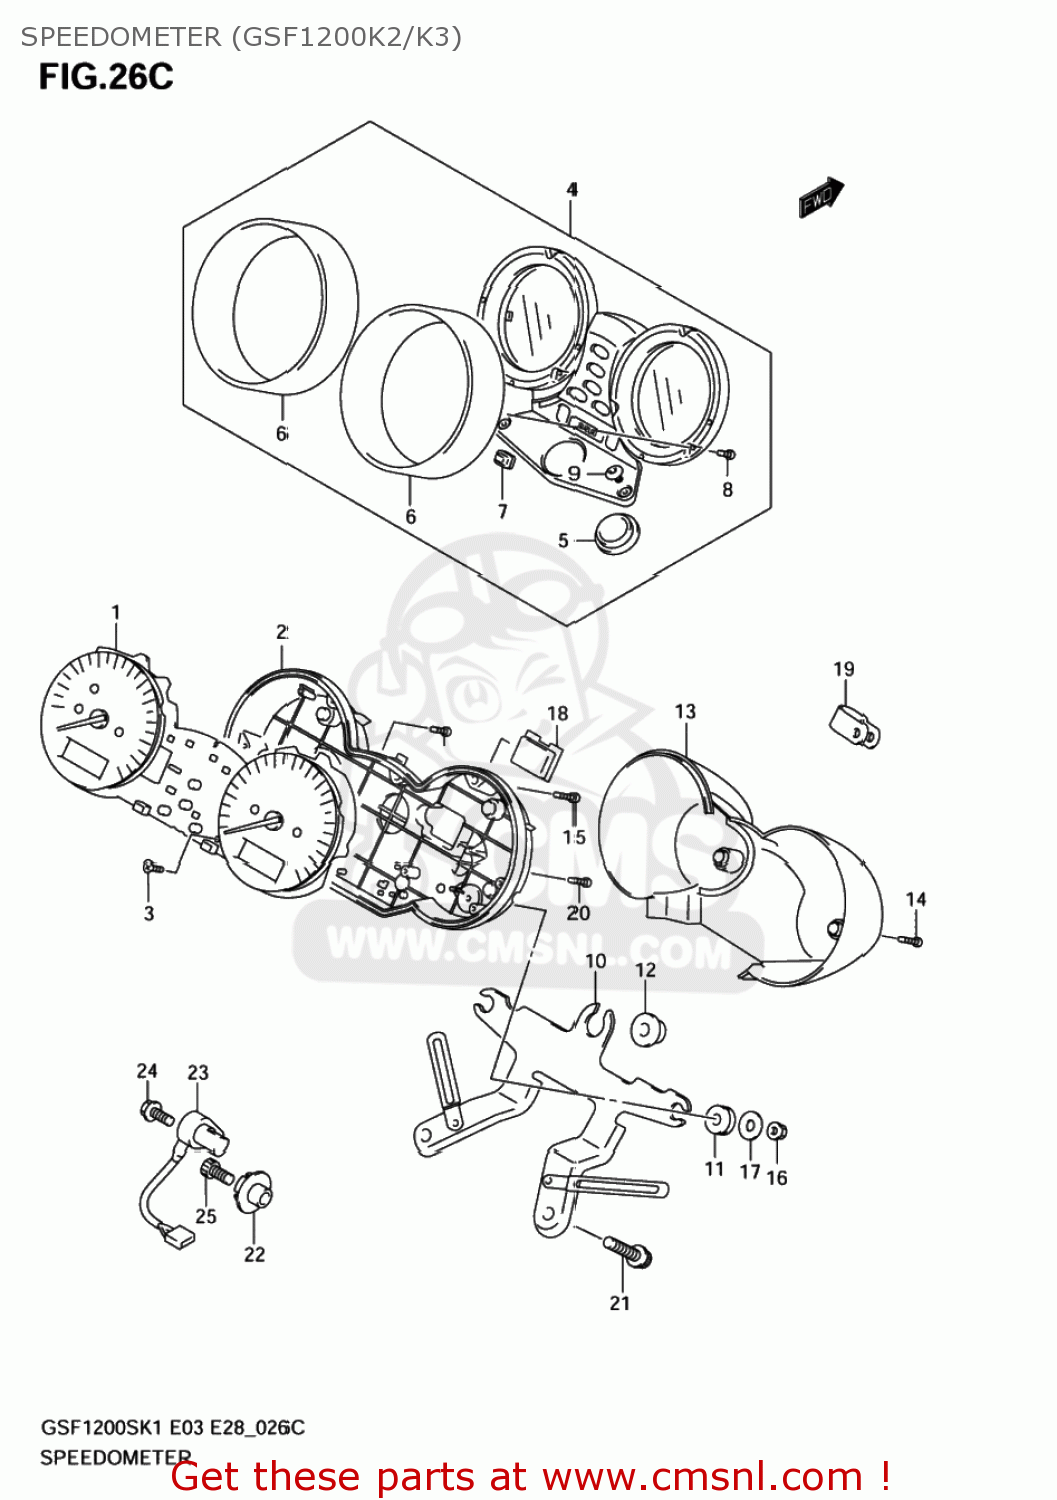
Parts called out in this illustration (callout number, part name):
1	SPEEDOMETER
2	CASE ASSY,LOWE
3	SCREW(4X14)
4	UPR CASE ASSY
5	DAMPER
6	RING
7	RUBBER,SWITCH
8	SCREW(2.3X8)
9	TAPPING CAP(5X10.2)
10	BRACKET
11	CUSHION
12	CUSHION
13	COVER
14	SCREW,PAN HEAD(3X14)
15	SCREW(3X16)
16	NUT
17	WASHER(5.2X16X1)
18	GROMMET
19	CLAMP
20	SCREW,PAN HEAD(3X16)
21	BOLT MAGNETO S
22	ROTOR,SPEED
23	SENSOR,SPEED
24	BOLT
25	BOLT
